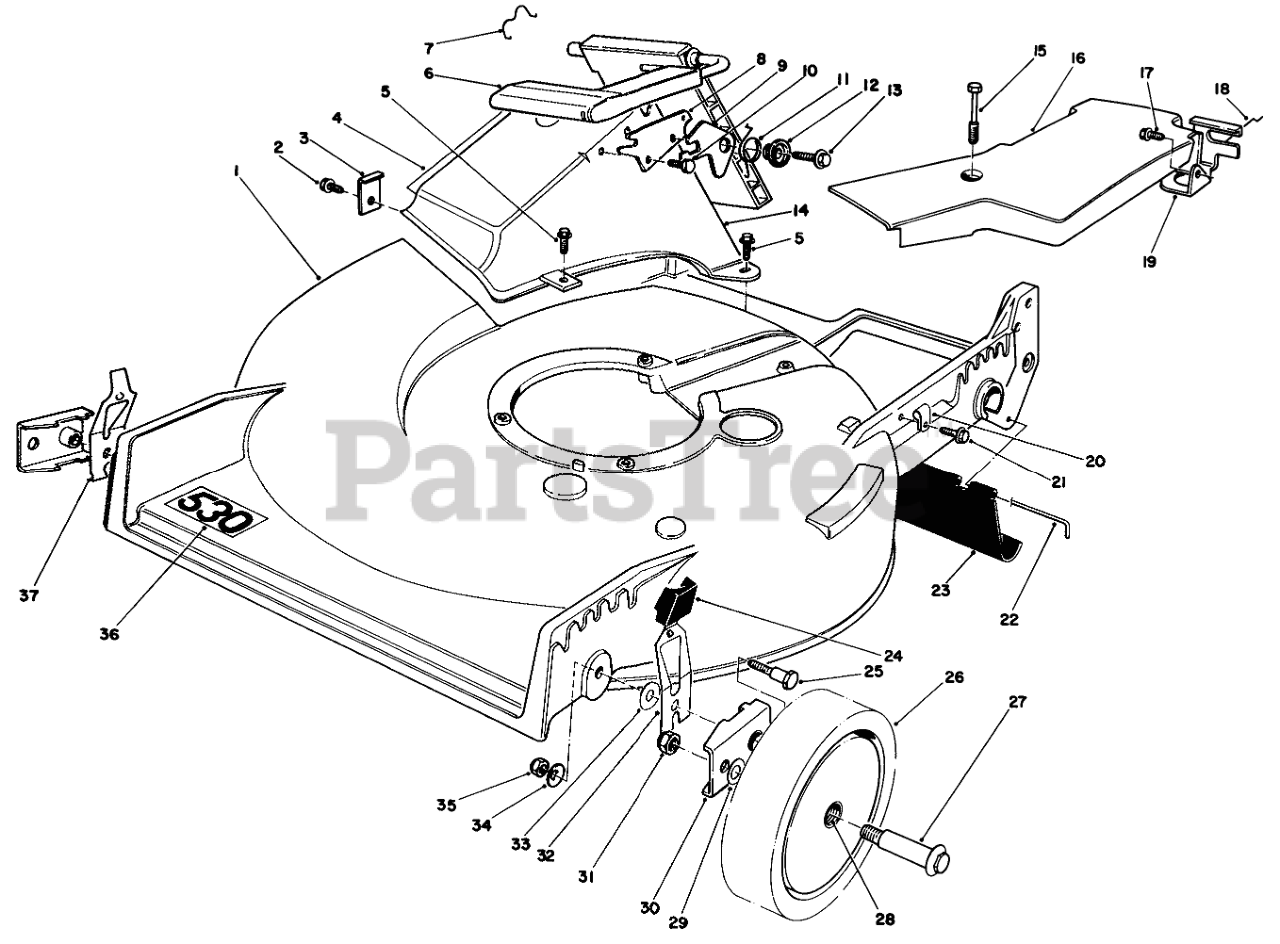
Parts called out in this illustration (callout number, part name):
1	21 SP RB HSG/DECAL
2	SCREW
3	TUNNEL CLIP
4	ATTENTION DECAL
5	SCREW-HWH
6	Discharge Door Assembly
7	DOOR RET SPRING
8	DOOR LATCH PLATE
9	SAFETY LATCH
10	SCREW-PLASTITE
11	TORSION SPRING
12	DOOR SPACER
13	SCREW-HWH
14	Tunnel Discharge
15	SCREW-HHFTF
16	Cover-Belt
17	SCREW-HWHTF
18	RETAINER-CABLE
19	Bracket-Traction Adj.
20	CLAMP-CABLE
21	SCREW
22	ROD-SHIELD
23	SHIELD-TRAILING
24	KNOB-ARM
25	PIVOT SCREW
26	Wheel & Tire Assembly (Incl. Ref. #29)
27	WHEEL BOLT
28	BUSHING
29	WASHER
30	HP PIVOT ARM ASM
31	NUT-LOCK
32	L. HP SPRING ARM ASM
33	WASHER-PIVOT
34	WASHER-BELLEVILLE
35	NUT-LOCK, NI
36	Decal-530
37	R HP SPRING ARM ASM
